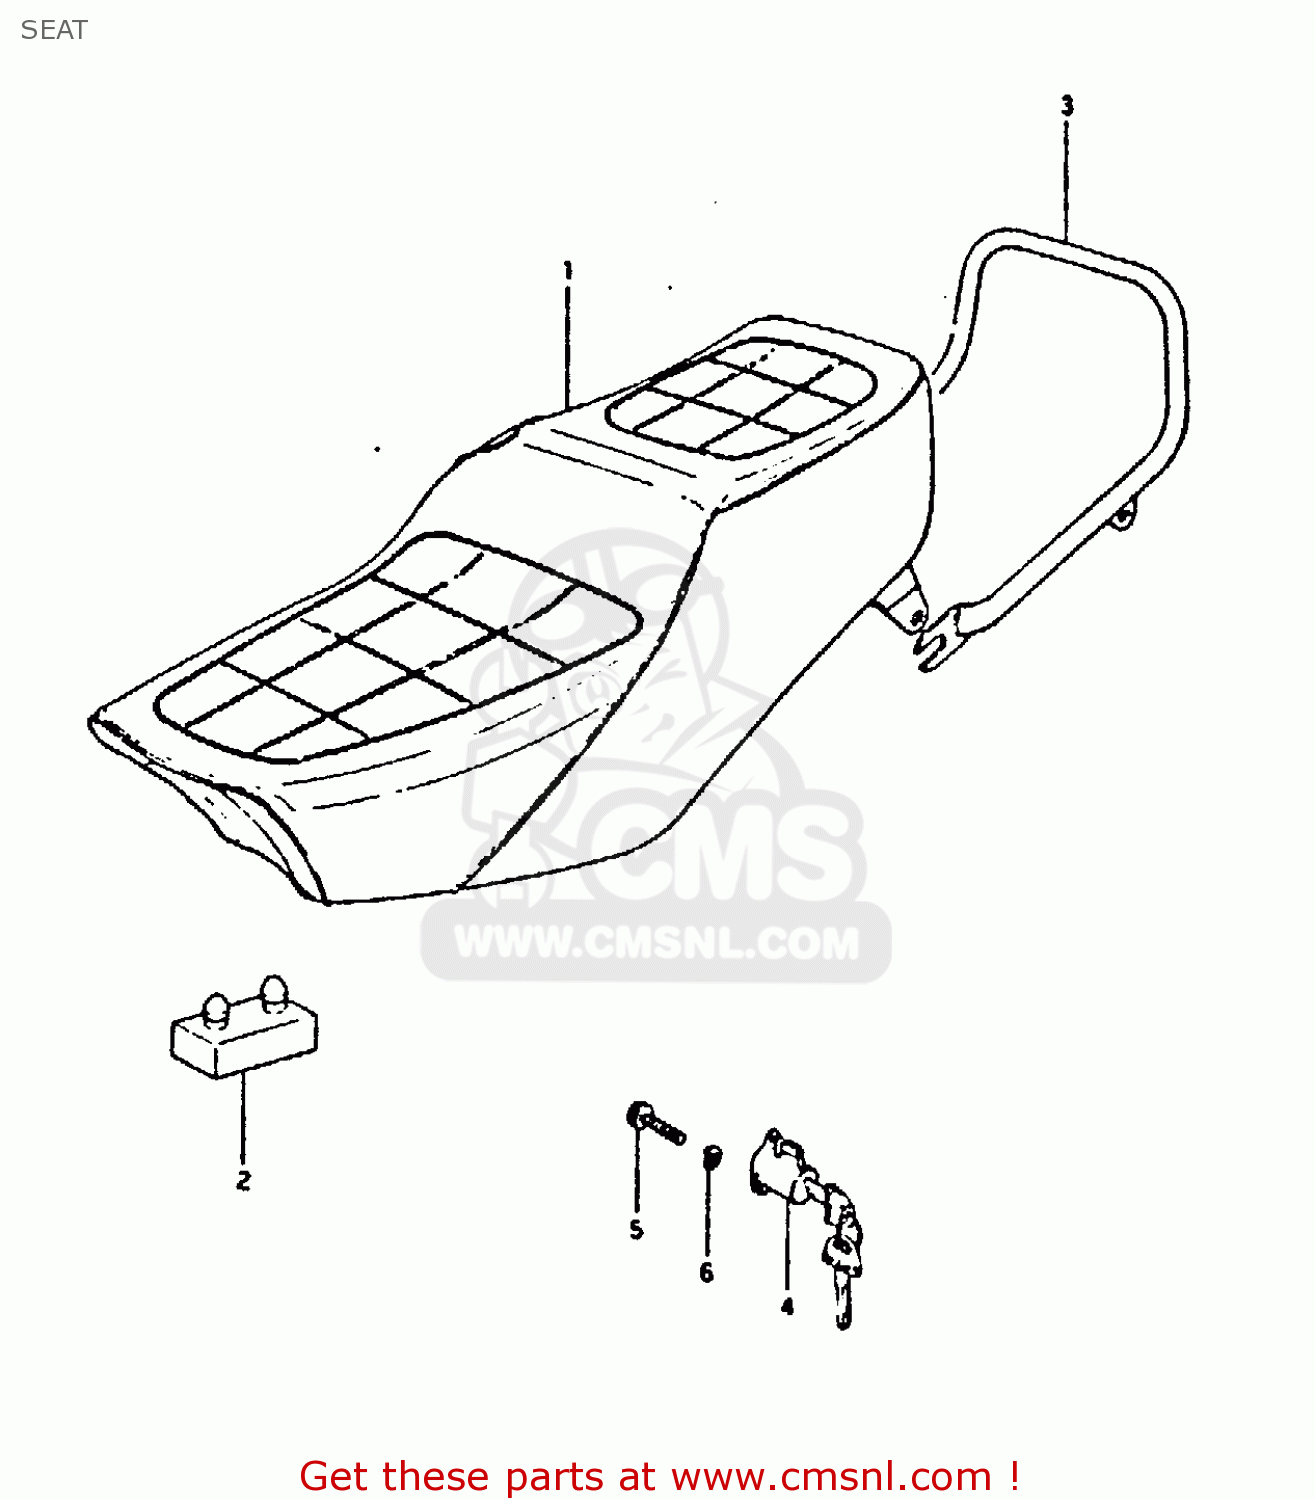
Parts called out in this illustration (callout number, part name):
1	SEAT ASSEMBLY
2	CUSHION
3	HANDLE,PILLION RIDER
4	LOCK ASSEMBLY,HELMET
5	BOLT 6X11
6	LOCK WASHER
